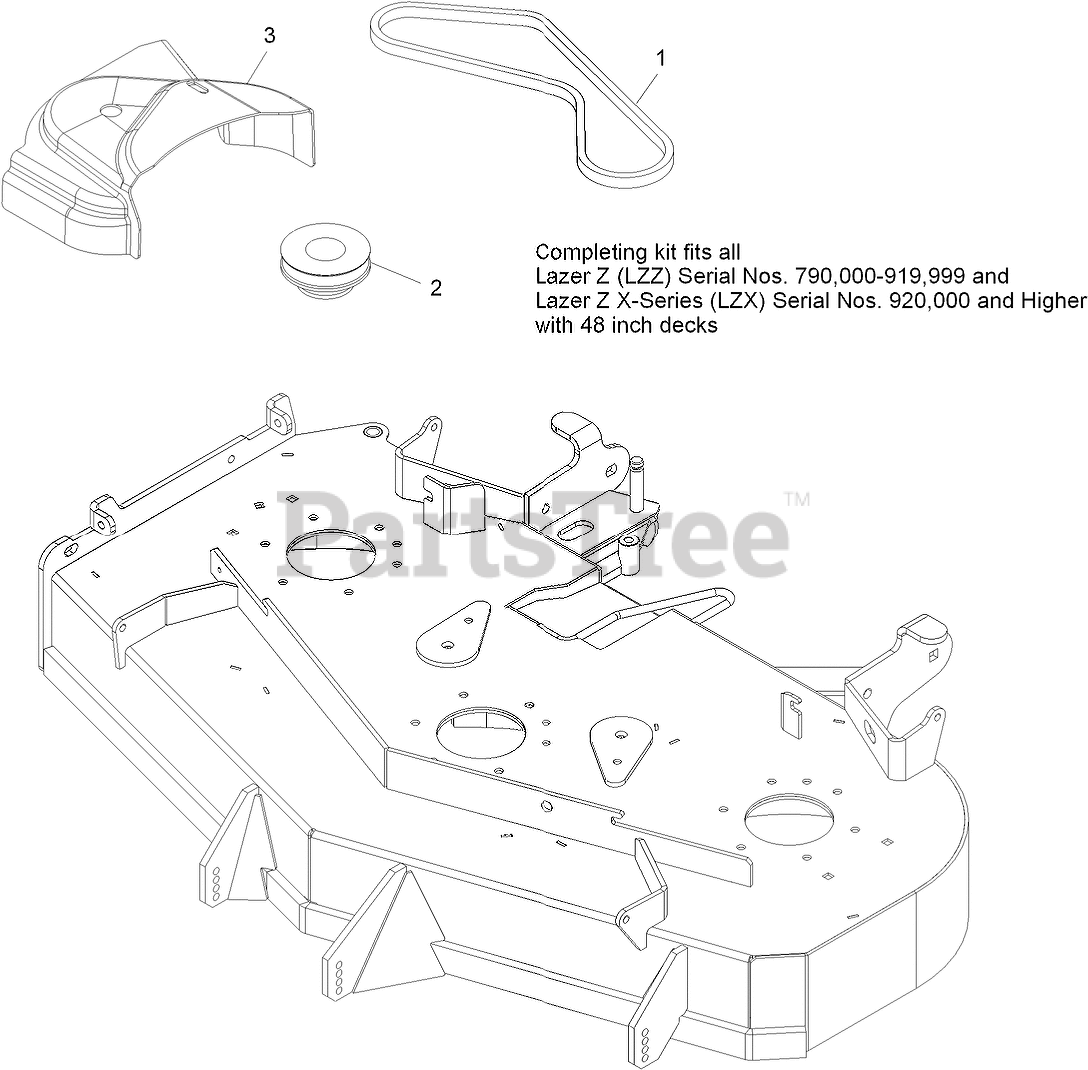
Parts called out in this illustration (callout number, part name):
1	BELT-BLOWER
2	SHEAVE,DRIVE LZUV 486
3	COVER,BELT UV 48
